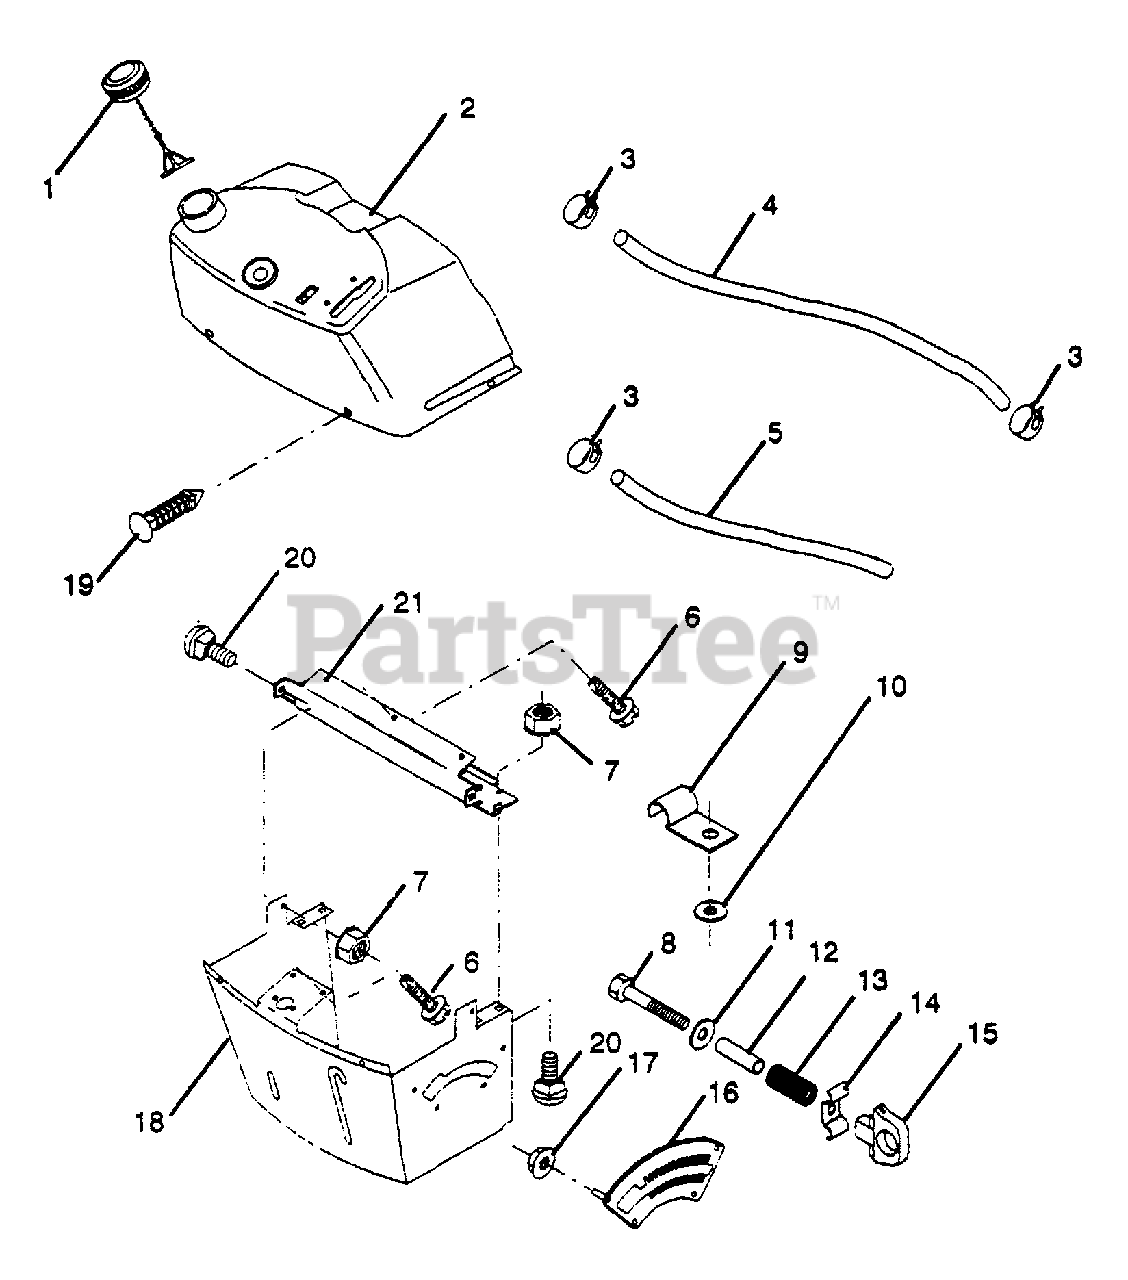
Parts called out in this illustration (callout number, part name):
1	Cap, Fuel
2	Assembly, Dash & Fuel Tank
3	Clamp, Hose
4	Line, Fuel
5	Line, Fuel
6	Screw, Hex Hd. Washer
7	Nut, Hex Keps 1/4-20
8	Bolt, Fin. Hex 1/4-20 x 2
9	Clip, Fuel line
10	Washer 9/32 x 3/4 x 16 Ga.
11	Washer 11/32 x 11 /16 x 16 Ga.
12	Spacer, Split
13	Spring
14	Clip, Height Adjustment
15	Knob, Height Stop
16	Adjustment, Quadrant Height
17	Nut, Self Thread 3/16-18
18	Support, Dash
19	Snap, Plastic
20	Bolt, Carriage 1/4-20 x 1/2 Gr. 5
21	Brace, Cross
